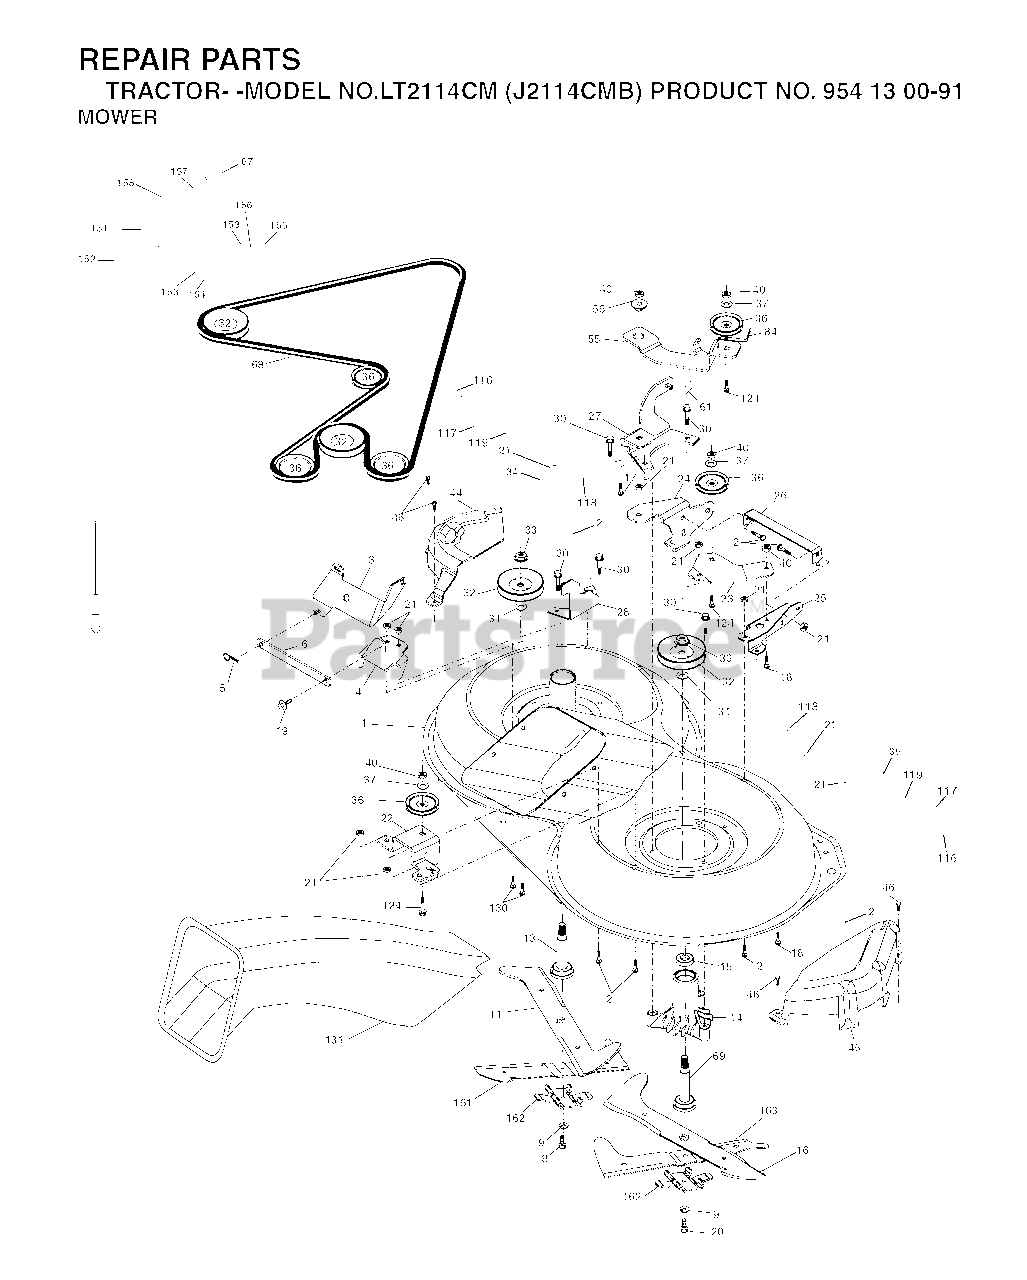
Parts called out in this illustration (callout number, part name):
1	MOWER HOUSING, DECK
2	BOLT
3	BRACKET
5	RETAINER-SPRNG RB
6	BAR SWAY
9	LOCKWASHER
11	BLADE-LH 5PT STAR(CTH130)
13	SHAFT ASM VENT
14	HSG MANDREL
16	BLADE RH 6PT STAR(CTH130)
17	BOLT.3/8-14X1.25
19	BOLT SHD 5/16-18
21	LOCKNUT
24	BRACKET
25	BRACKET
26	BRACE
28	BRACKET
30	SCREW, WASHER HEAD
31	WASHER
32	PULLEY, MANDREL
33	NUT, FLG TOPLOCK 9/16"
36	PULLEY.IDLER.4.25
40	LOCKNUT
45	MANDREL COVER
46	SCREW.1/4-20X5/8
55	ARM IDLER
56	SPACER.RETAINER.MOWER
61	SPRING.TENSION.BELT
67	KNOB T (3/8 HOLE)
68	HEX-BELT
69	SHAFT.ASM.W/LWR.BRG.RH.THREAD
84	KEEPER, BELT IDLER
116	SHOULDER BOLT
117	WHEEL GAGE DONUT
118	LOCKNUT
119	WASHER
124	BOLT.3/8-16X1.50
131	CHUTE BAGGER
151	BRACKET, CLUTCH CABLE
153	WASHER FLAT 3/8"
154	SPRING RETAINER
155	SPRING RETENTION LEVER
156	SPACER CLUTCH CABLE
157	ROD CLUTCH CABLE 3/8"
158	SCREW
